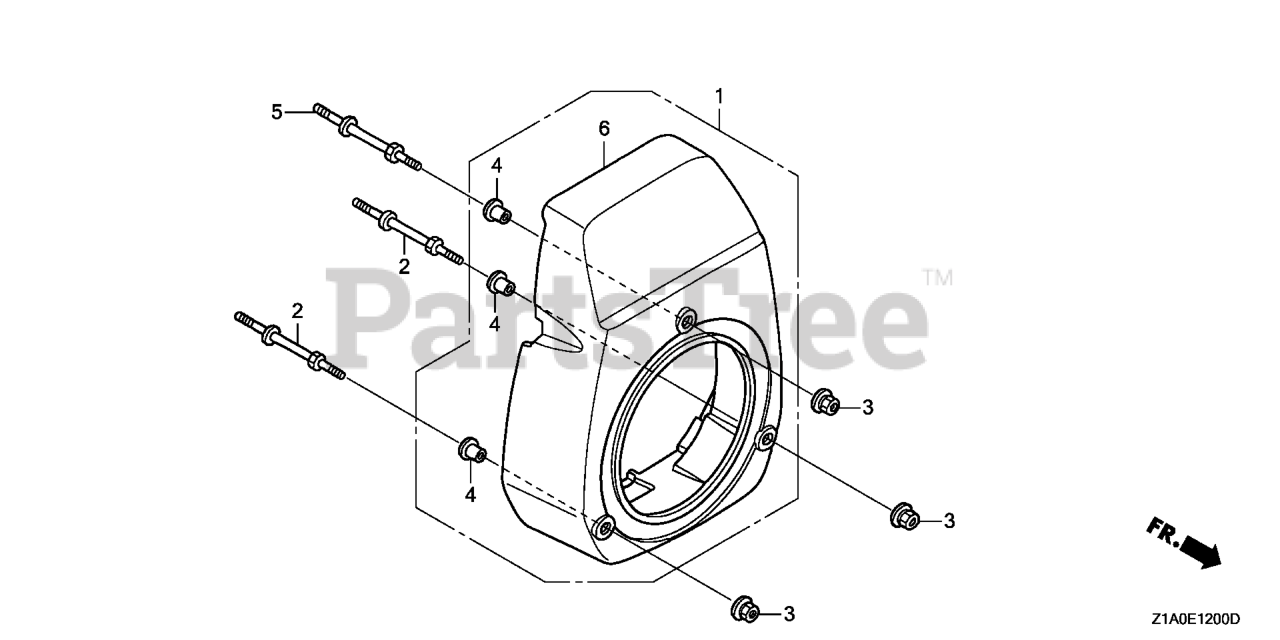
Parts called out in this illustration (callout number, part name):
1	COVER, FAN *R280* (POWER RED)
2	BOLT, STUD
3	NUT, FLANGE (6MM)
4	COLLAR, FAN COVER (Honda Code 5580527). (N/A: SEE ASSEMBLY)
5	BOLT, STUD
5	BOLT, STUD (H=39.5MM)
